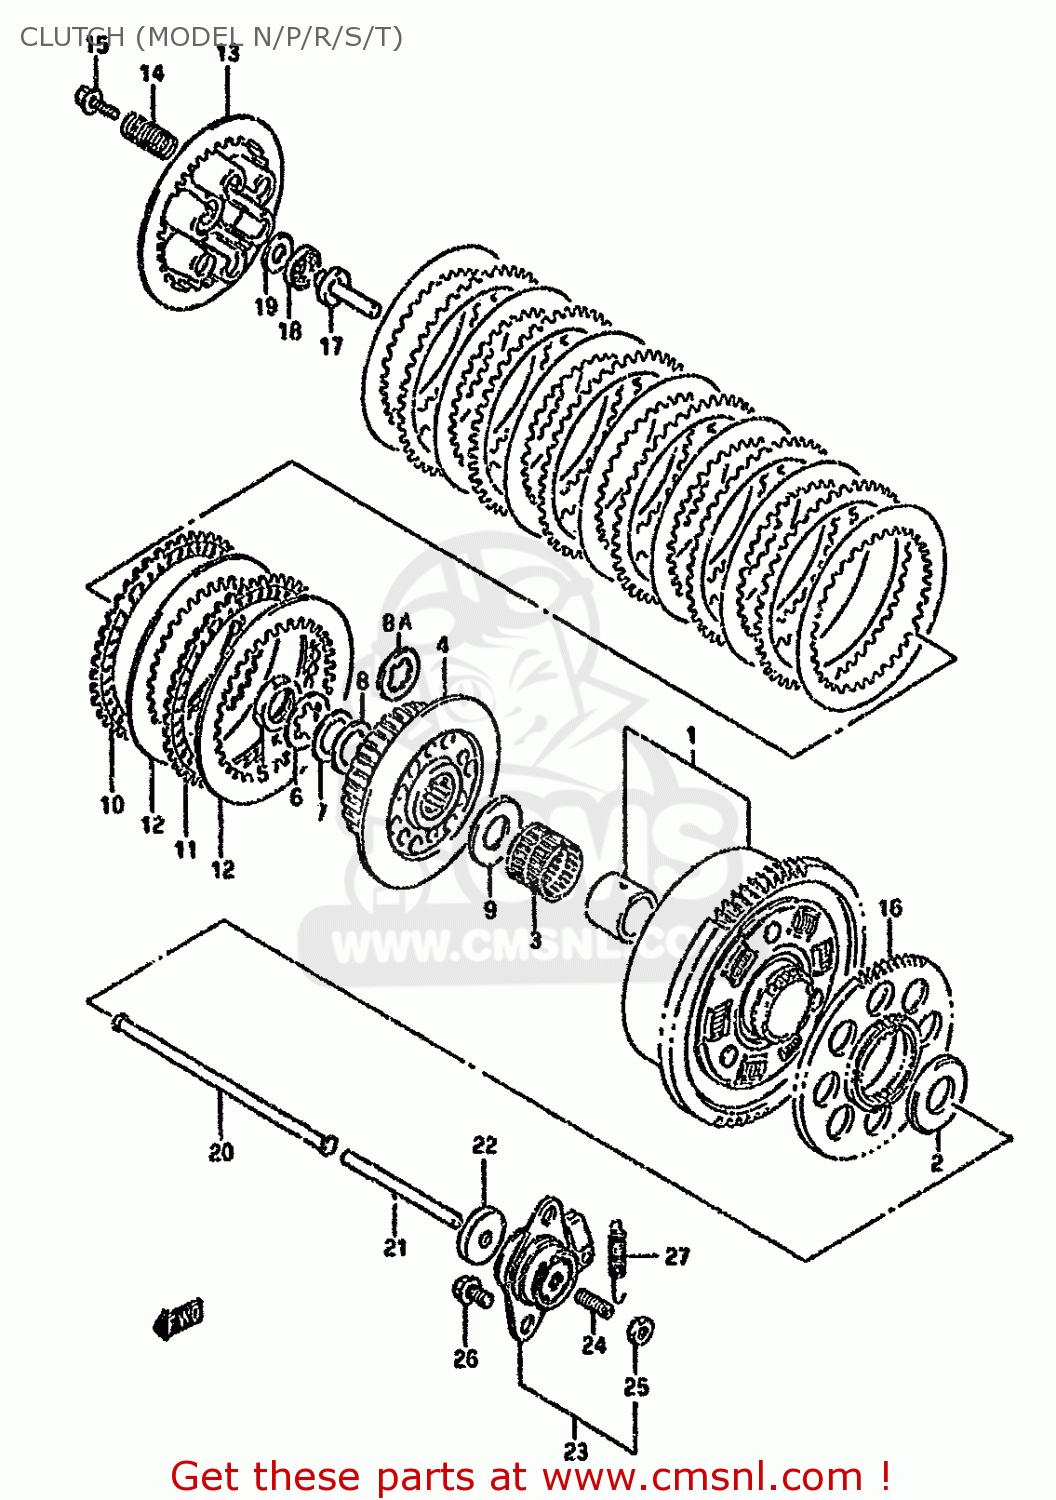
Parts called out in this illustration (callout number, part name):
1	GEAR ASSEMBLY,PRIMARY DRIVE
2	WASHER(25X54X2.5)
3	BEARING(35X40X35.8)
4	HUB,CLUTCH SLEEVE
5	NUT
6	WASHER,LOCK
7	WASHER
8	SHIM
8A	WASHER,LOCK
9	WASHER(25X50X2.5)
10	PLATE,CLUTCH DRIVE (NAS)
11	PLATE,CLUTCH DRIVE NO.2 (NAS)
12	PLATE,CLUTCH DRIVEN (NAS)
13	DISC,CLUTCH PRESSURE
14	SPRING
15	BOLT(6X25)
16	GEAR,GENERATOR DRIVE,N
17	PIECE,CLUTCH PUSH
18	BEARING(15X28X2)
19	WASHER
20	ROD,CLUTCH PUSH,R
21	ROD,CLUTCH PUSH,L
22	SEAL,OIL(6X34X5.5)
23	SCREW ASSY,CLUTCH RELEASE
24	SCREW(6X25)
25	NUT
26	BOLT
27	SPRING
